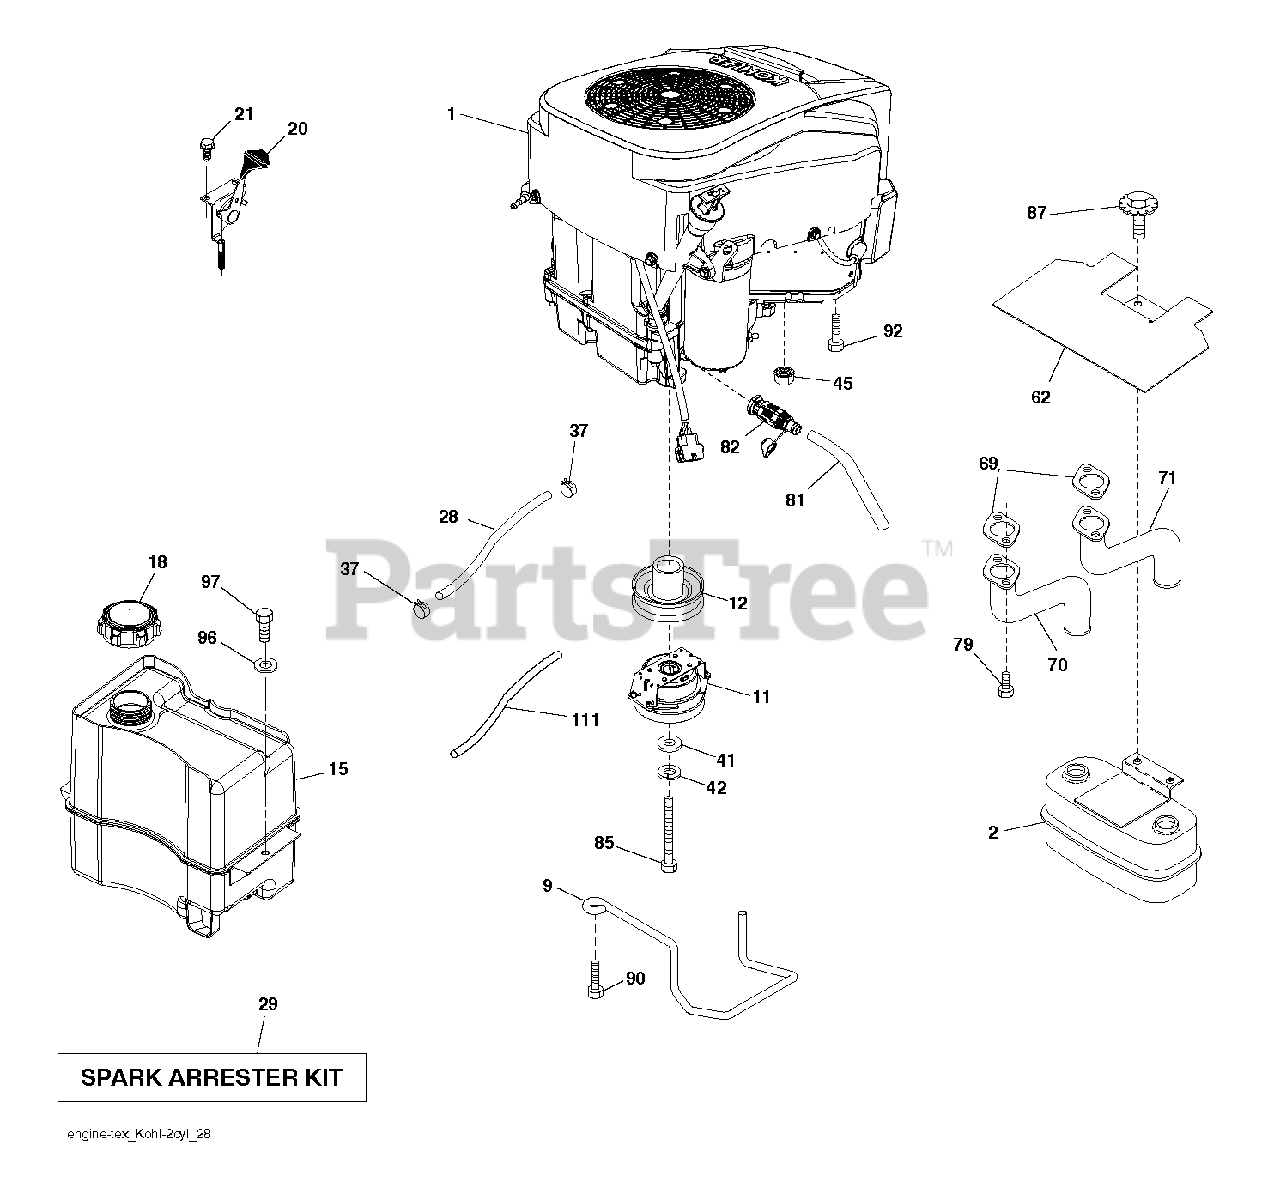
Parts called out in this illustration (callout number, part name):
2	MUFFLER.TWIN.CYL.LOW.TONE
9	KEEPER.BELT.ENGINE.3.25
11	Clutch, Ogura 5.0Pd Gt1.5A-Eh07
12	PULLEY.ENGINE.ENX
15	TANK.ASM.FRT.2.5 GAL.W/CAP.EPA
18	CAP.FUEL.2 WAY VENT
20	THROTTLE CONTROL
21	SCREW.#10 X 0.750.BOS (2 2)
28	LINE.FUEL.20"FRONT.EMI
29	SPARK ARRESTOR KIT
37	HOSE CLAMP
42	LOCKWASHER
45	NUT
62	SHIELD.HEAT.MUFFLER
69	GASKET.EXHAUST.KOHL.CV18-CV26
70	Exhaust Pipe, LH CV18/20
71	Exhaust Pipe, RH CV18/20
79	SCREW.SOCKET HD.5/16-1
81	TUBE, DRAIN OIL ASM.
82	VALUE.OIL.DRAIN
85	BOLT HEX 7/16-20 X 3.75 GR. 5
87	BOLT, 5/16-18 X 1 3/4
90	SCREW 3/8-16X1
92	SCREW 3/8-16X1
97	SCREW HEXWSHR 1/4-20X3/4
111	RP PURGE LINE
